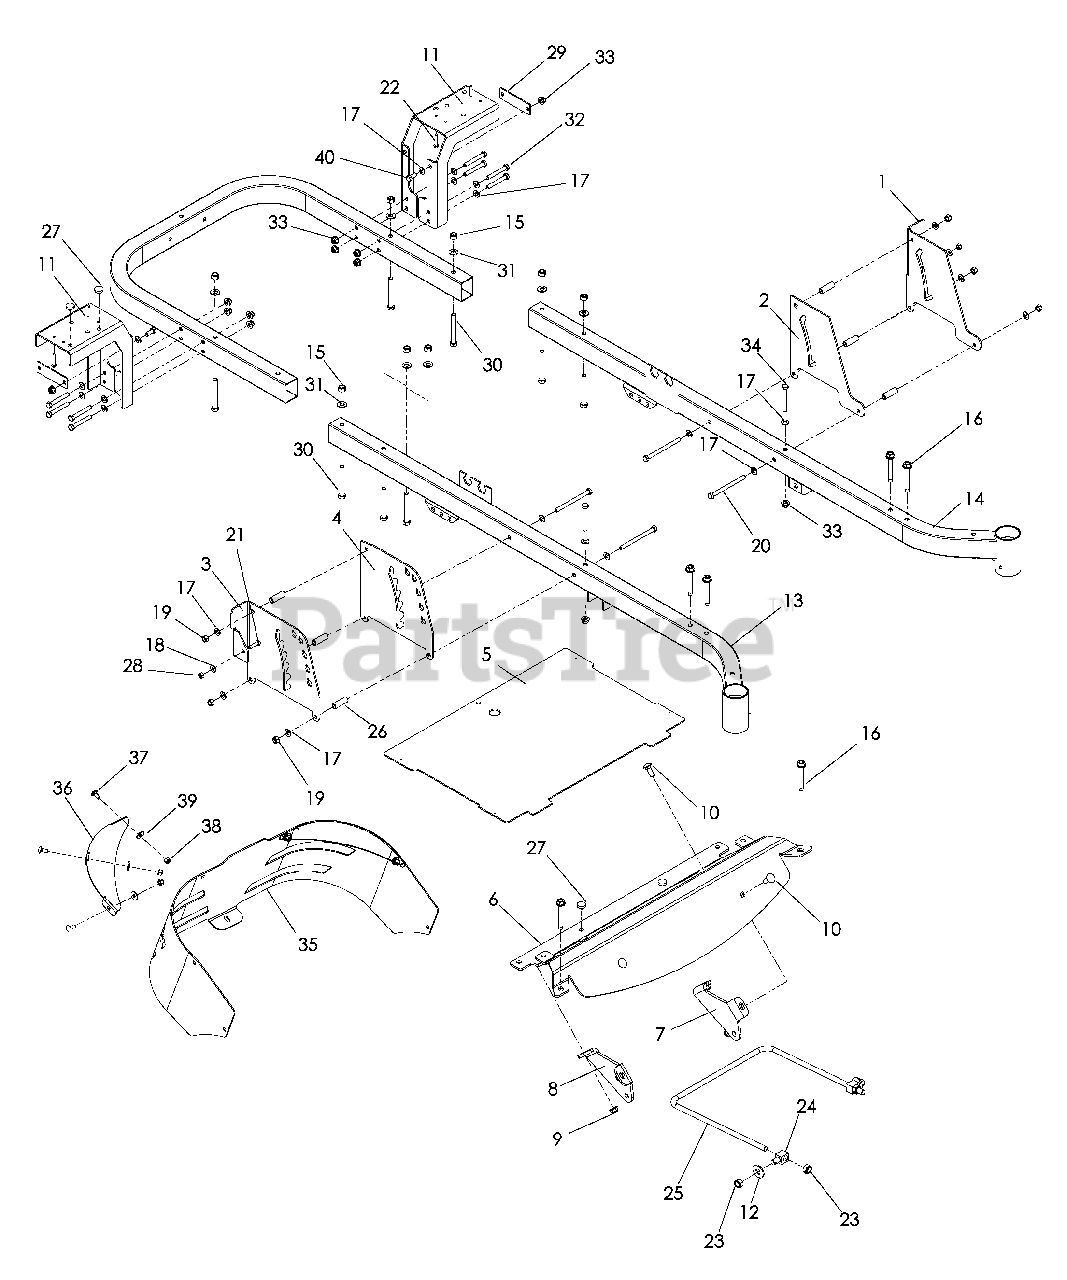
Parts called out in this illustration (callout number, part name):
1	PLATE, OUTER BRAKE
2	PLATE, BRAKE LATCH
3	PLATE, OUTER HEIGHT
4	PLATE, INNER HEIGHT
5	FOOT PLATE w/DECALS
7	MOUNT, STRUT, RT
8	MOUNT, STRUT, LT
9	NUT 3/8-16 HEX FLG NYLOC
10	RHSNB 3/8-16 x 1
11	SUPPORT, FENDER
12	WASHER ½ FLAT
13	FRAME, FRONT RT
14	FRAME, FRONT LT
15	NUT 3/8-16 HEX NYLOC
16	BOLT 3/8-16 x 25/8 THD FRM
17	WASHER 5/16 SAE FLAT
18	WASHER ¼ FLAT SAE
19	NUT 5/16-18 HEX NYLOC
20	HCS 5/16-18 x 4
21	HCS ¼-20 x 1
22	SCREW 10-12 x 1¼ WSH HD
23	NUT 7/16-14 HEX NYLOC
25	LINK, FRONT SUSPENSION
26	SPACER ½ OD x 1½
27	GROMMET, BUMPER
28	NUT ¼-20 HEX NYLOC
29	PLATE, REINFORCEMENT
30	HCS 3/8-16 x 3
31	WASHER 3/8 SAE FLAT
32	HCS 5/16-18 x 2¼
33	NUT 5/16-18 FLANGE NYLOC
34	HCS 5/16-18 x 2¾
35	GUARD, WIDE ENGINE
36	SUPPORT, CORNER
37	RHSSNB ¼-20 x 5/8
38	NUT ¼-20 HEX NYLOC
39	WASHER ¼ FLAT
40	HCS 5/16-18 x ¾
